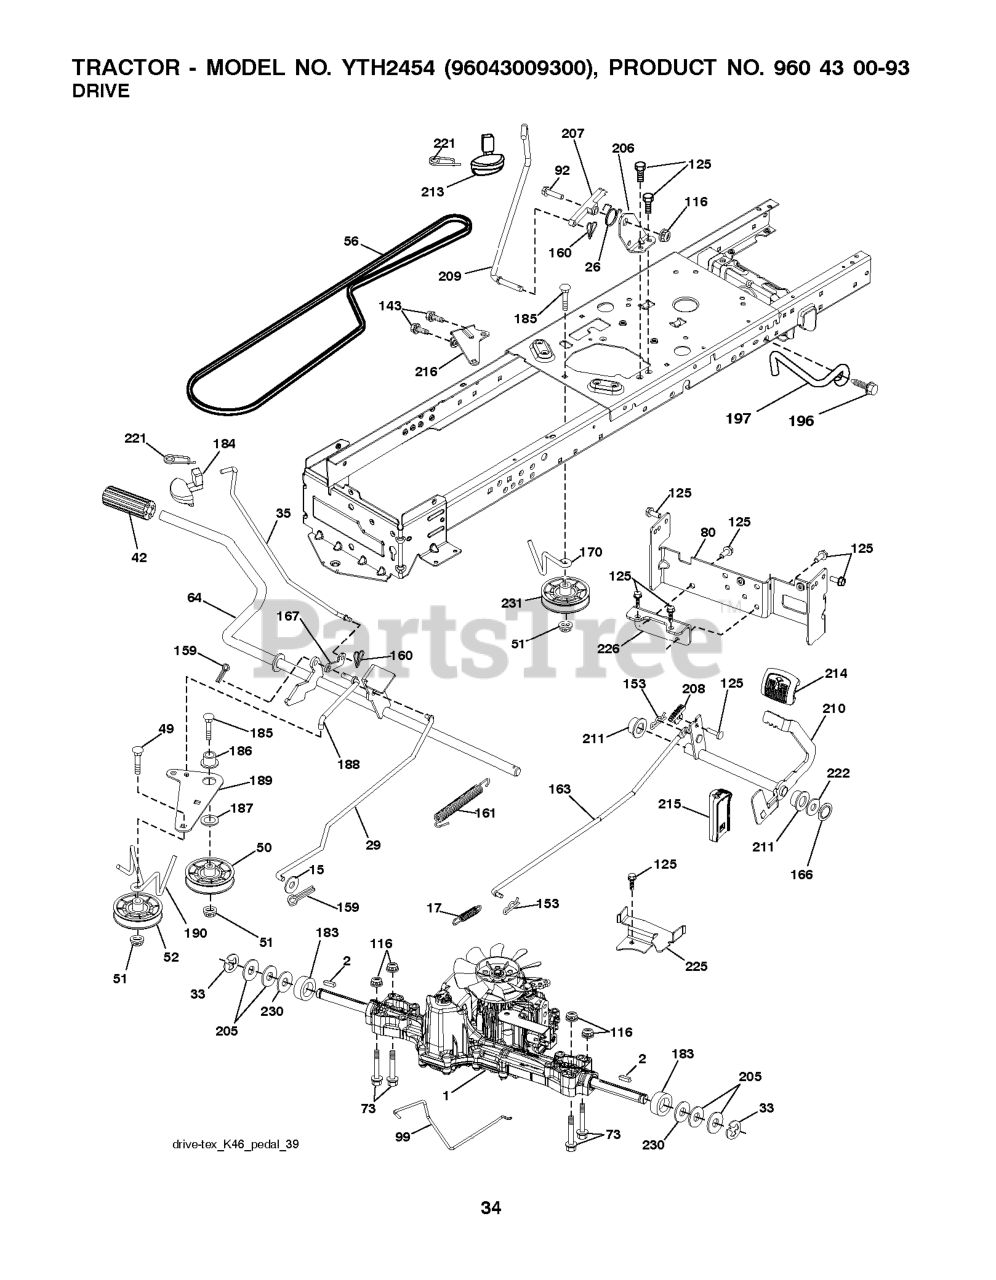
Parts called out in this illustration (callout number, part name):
1	TRANSAXLE(K46BT).PDL.
2	SQUARE KEY
15	WASHER
17	SPRING.BRAKE.K46.GREEN
26	SPRING.RETURN.CRUISE
29	ROD.BRAKE.K46
35	ROD.BRAKE.PARKING.GT.H
42	PEDAL COVER T
50	IDLER.FLAT.910.OFFSET
51	NUT LOCK FLG 3/8-16 UNC
52	IDLER.V-GROOVE.910.OFFSET
56	V-BELT.MOWER.92.40.42/K46
64	SHAFT.ASM.PEDAL.BRK.CNTR
73	BOLT HEX 5/16-18 GR 5
80	STRAP TORQUE
92	BOLT
99	ROD.SPRING.BYPASS.K46.LT.Z
116	NUT LOCK HEX FLANGE 5/16-18
125	SCREW
143	Screw 5/16-18 x 1/2 Hex, Self Tapping 5/16-18 x 1/2
153	RETAINER M
159	COTTER PIN
160	RETAINER CLIP
161	SPRING, RETURN LT
163	ROD.CONTROL.PEDAL.K46
166	NUT.PUSH.625
167	LATCH.BRAKE.SPRING
170	KEEPER.CENTER SPAN.1.688
183	SPACER AXLE
184	HANDLE.PARKG.BRK.HUSQ X667
186	SPACER.RETAINER
187	WASHER 12/32X2X10GA
188	RP.LINK.CLUTCH.GROUND.DRIVE
189	BELLCRANK.GROUND.DRIVE.TEX.
190	KEEPER.BELLCRANK.DRIVE
196	SCREW 3/8-16X1
197	LINK.CLUTCH.ANIT-ROTAT
206	BRKT.MOUNT.LATCH.CRUIS
207	LATCH.CONTROL.CRUISE
208	GEAR.SECTOR.CONTROL.CR
209	ROD.CONTROL.CRUISE.GT.
210	ROCKER.ASM.PEDAL.CONTR
211	BEARING.NYLON
213	KNOB.CONTROL.CRUSIE.HU
214	PEDAL.FORWARD.PAD.TEX
215	PEDAL.REVERSE.TEX.GT.4
216	BRACKET.PULLEY.IDLER.W/TEX
221	RETAINER.SPRING.CLIP.H
222	WASHER 21/32 X 1-1/4 X 10 GA.
225	KEEPER.BELT.TRANSAXLE.K46
226	BRACKET.MOUNT.TORQUE.K46.TLT
230	WASHER.HARDENED
231	IDLER.V-GROOVE.1.688.OFFSET
